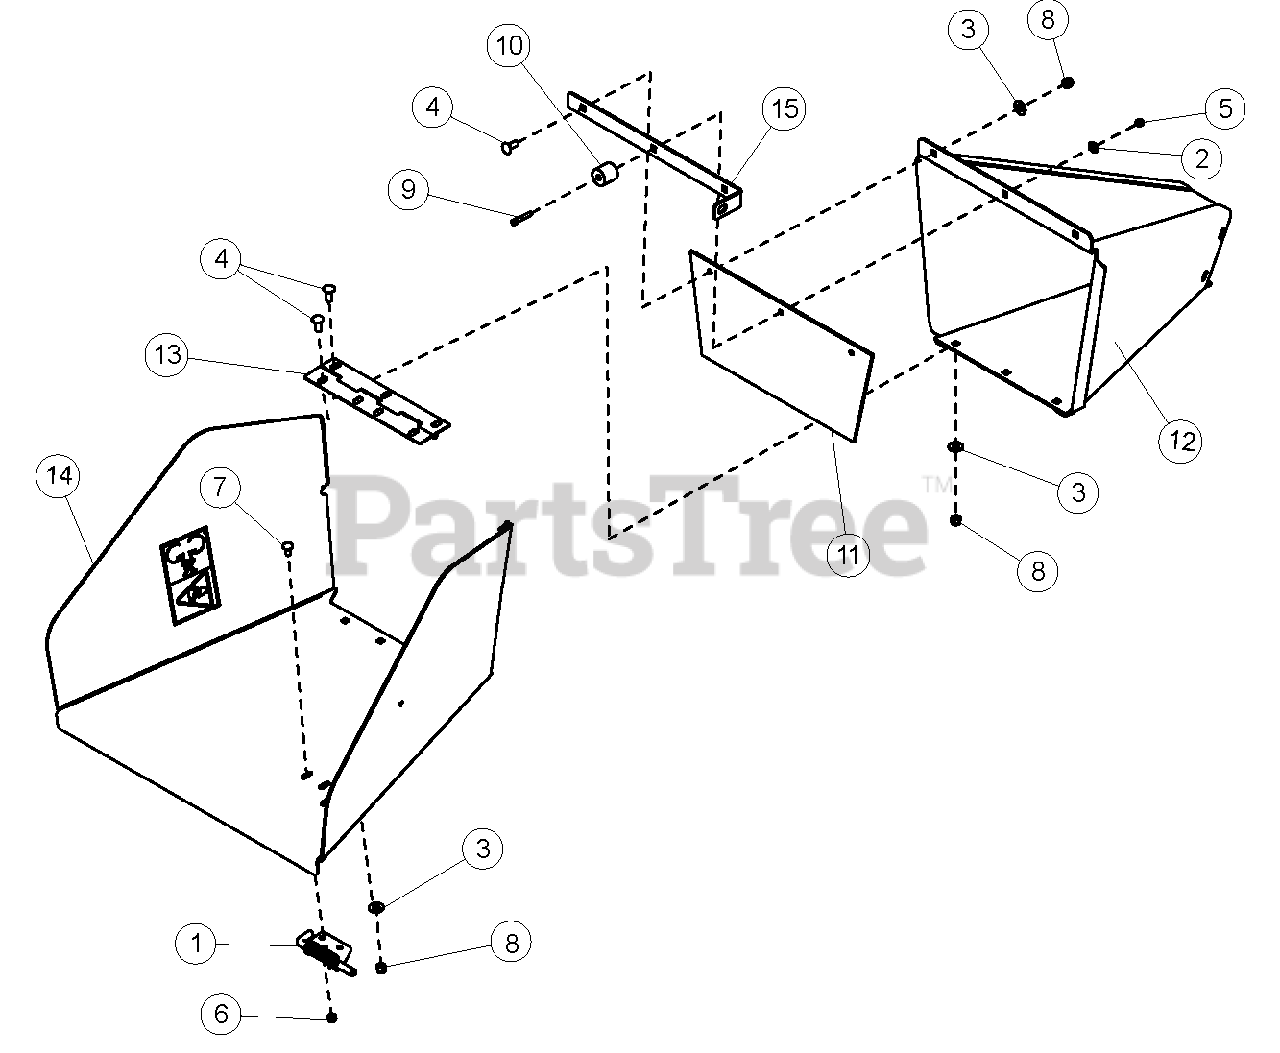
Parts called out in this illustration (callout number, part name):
1	LATCH, RH HINGE
2	WASHER, 1/4" FLAT
3	WASHER, 3/8" FLAT
4	BOLT, 3/8 X 1" CRG
5	NUT, 1/4" NYLOCK
6	NUT, 5/16" NYLOCK
7	BOLT, 5/16 X 3/4" CRG
8	NUT, 3/8" NYLOCK
9	SOC HD CAP SCREW 1/4 X 1-1/2"
10	BUMPER, RECESSED RUBBER
11	FLAP, CHIPPER CHUTE
12	WELDMENT, HOPPER
13	HINGE, CHUTE EXTENSION
14	ASSEMBLY, 4-1/2" EXTENSION TRAY
15	STRIP, FLAP RETAINER
